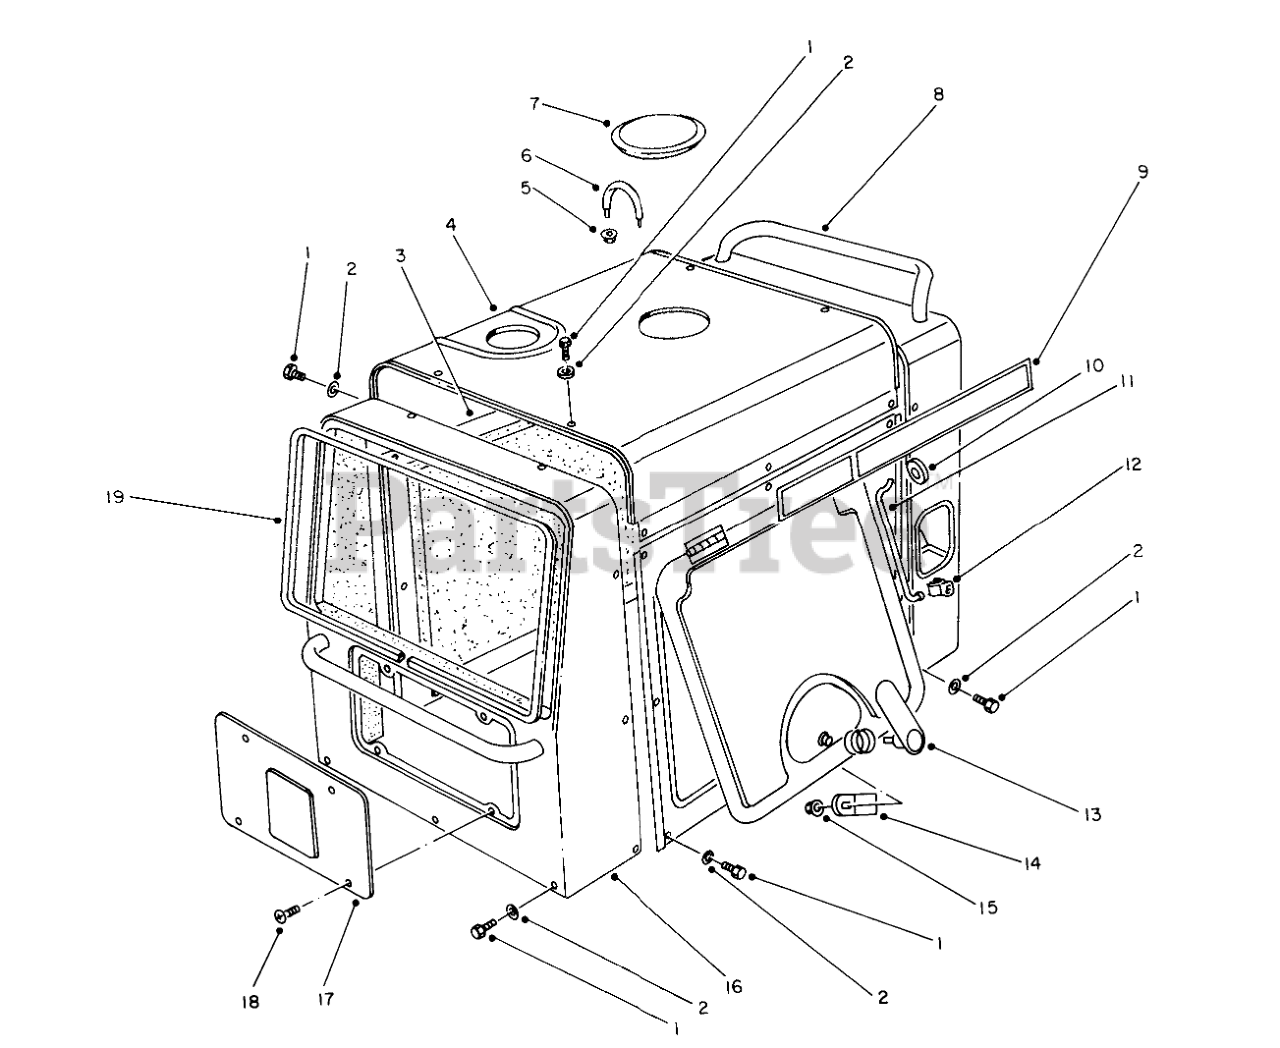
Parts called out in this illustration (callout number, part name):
2	Washer
3	Cover L.H.
4	Cover-Upper
6	U-Bolt
8	Cover-Rear
9	Decal-Toro
10	Grommet
11	Rod-Door Stop
12	Clamp
13	Handle-Door
14	Plate-Handle
16	Cover-Front
17	Lid-Terminal
18	Screw
19	Seal-Front Cover
